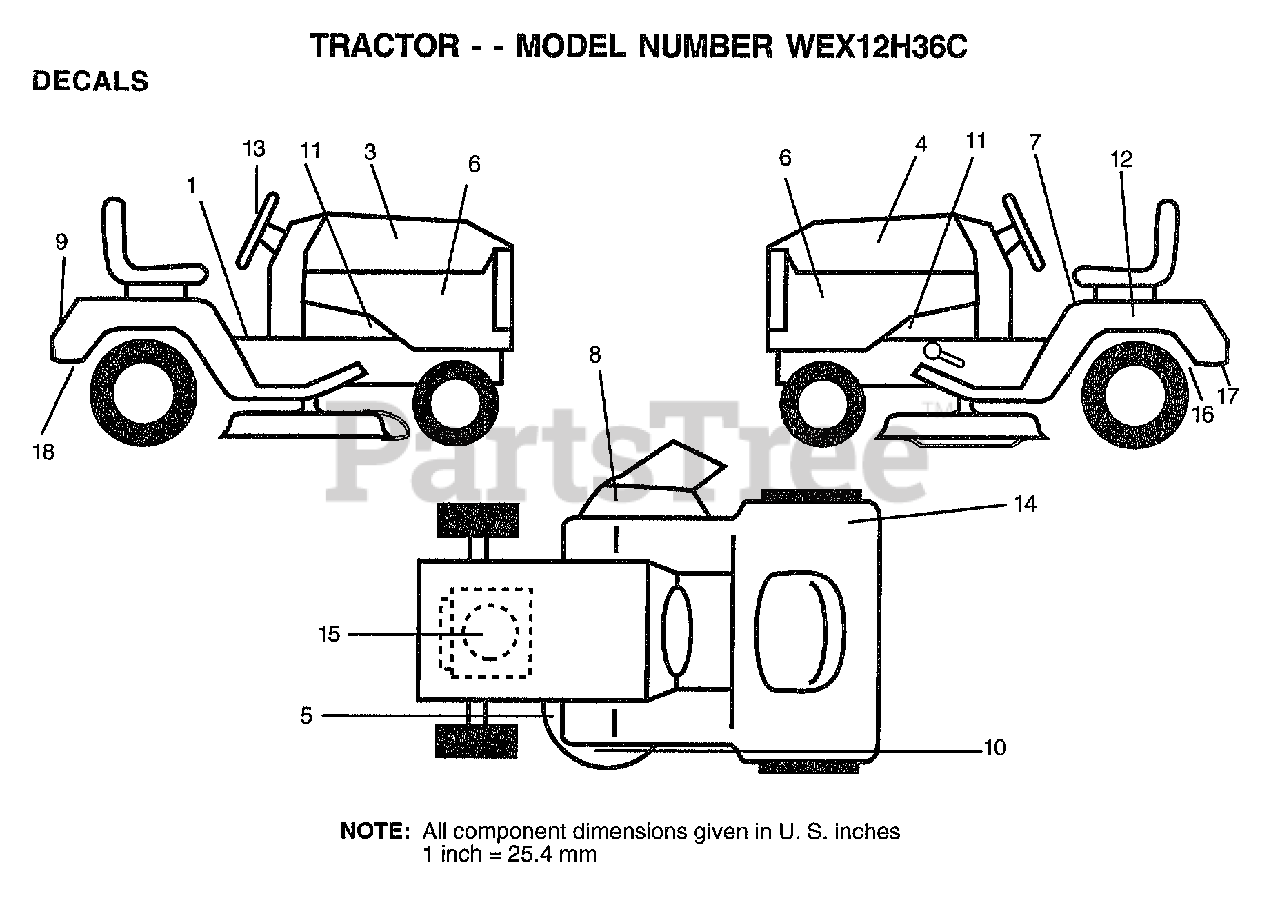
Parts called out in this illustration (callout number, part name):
1	DECAL CLUTCH/BRAK
3	DECAL.HOOD.RH
4	DECAL.HOOD.LH
5	DECAL.V.BELT
6	"DECAL,PNL SIDE"
7	DECAL.READ.O.MANU
8	DECAL.DANGER.CUTF
9	DECAL.FENDER.LOGO
10	DECAL, DECK GRASSEATER
11	"DECAL CHASSIS,HOT"
12	DECAL.BATRY.3-3908
13	DECAL INSRT STEER
15	DECAL, ENGINE
16	DECAL.DRAWBAR.LDL
17	DECAL.DRAWBAR.CTL
18	DECAL.EURO.ST.CE.
